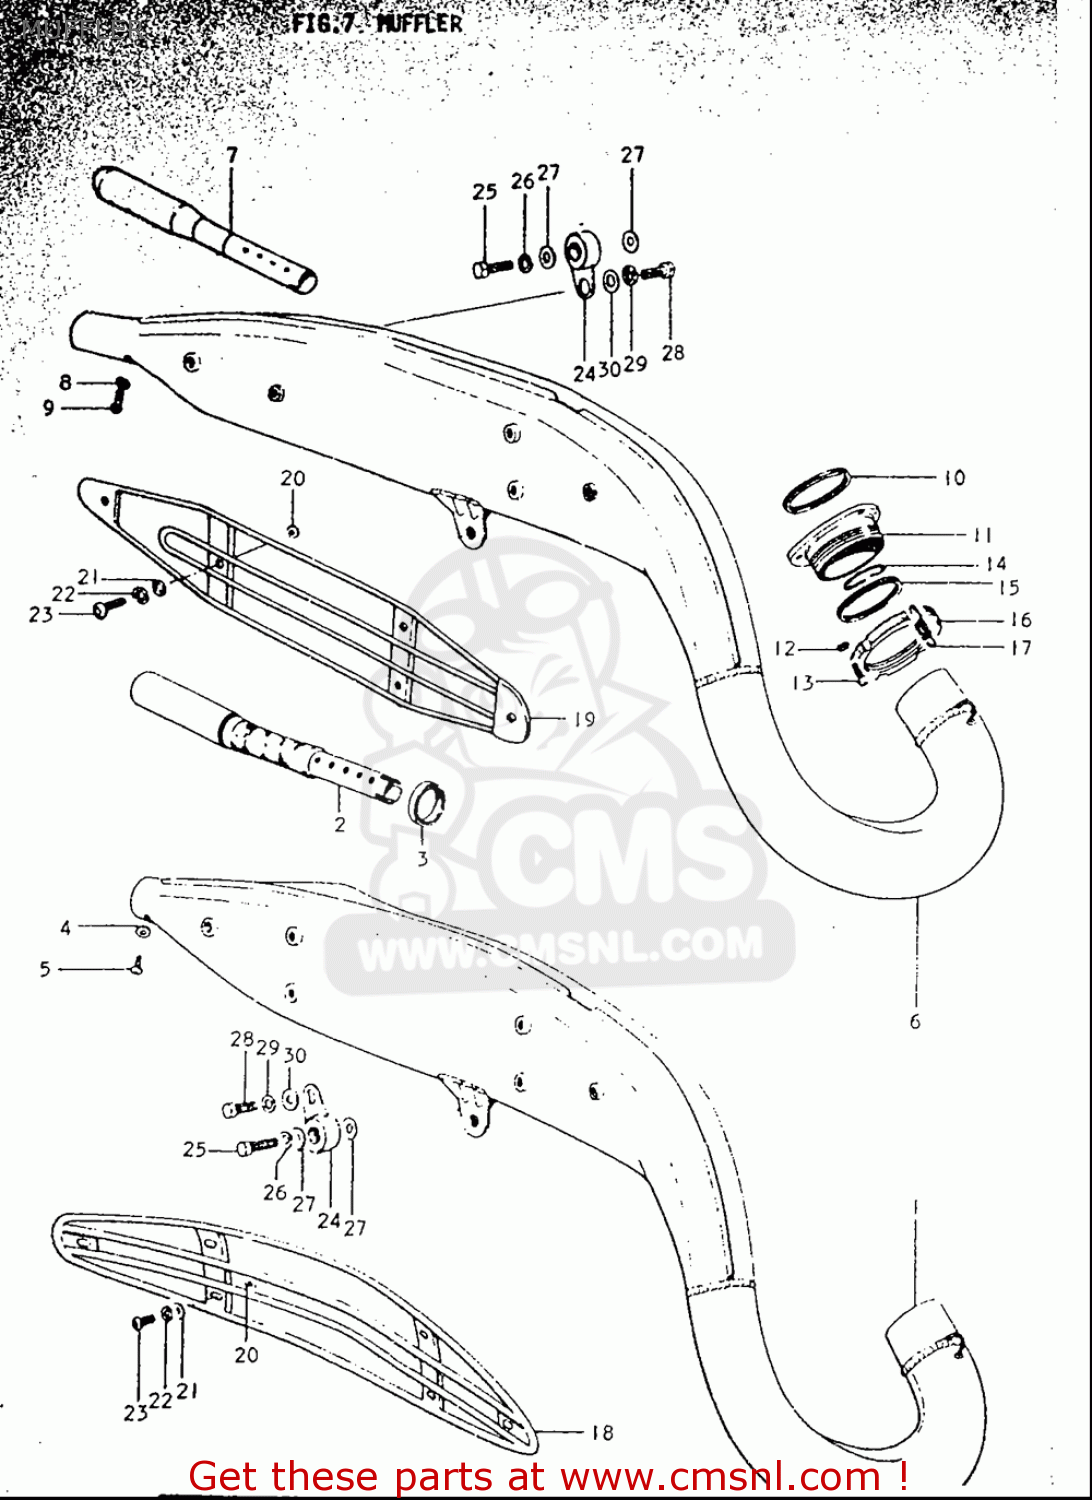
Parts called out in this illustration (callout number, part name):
8	GASKET(6.2X12X1.5) (NAS)
10	GASKET,EXHAUST PIPE (NAS)
12	WASHER,LOCK
13	SCREW
15	CLAMP,EXHAUST PIPE
16	HOLDER,EXHAUST PIPE CLAMP
17	SPRING
20	GASKET(6.2X12X1.5) (NAS)
21	WASHER
22	WASHER,LOCK
23	SCREW
25	BOLT
26	WASHER,LOCK
27	WASHER
28	BOLT
29	WASHER,LOCK
30	WASHER
